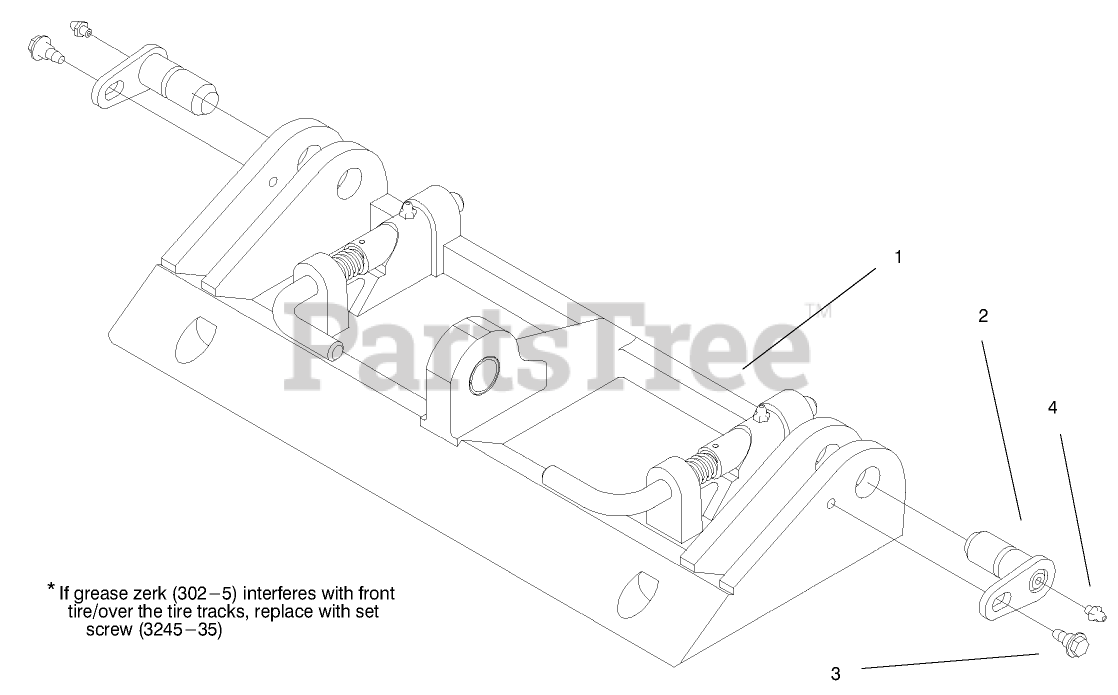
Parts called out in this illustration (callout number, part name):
1	QUICK ATTACH ASM
2	PIN-PIVOT
3	BOLT-SHOULDER
4	FITTING-GREASE
